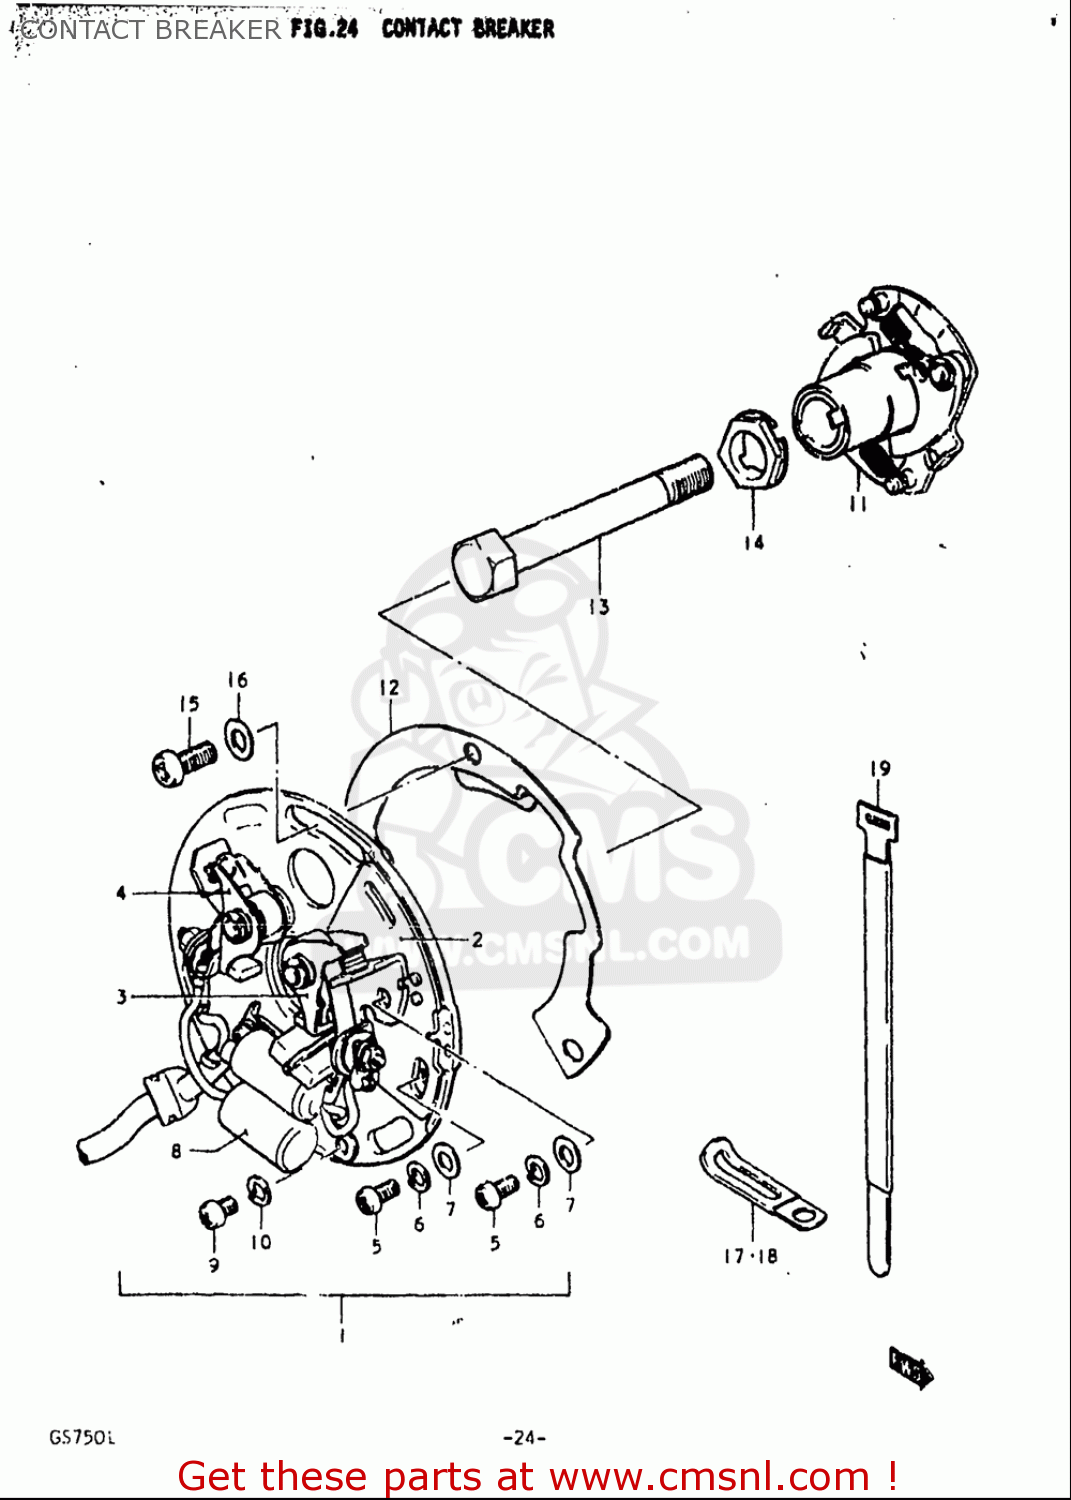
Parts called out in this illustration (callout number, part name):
1	BREAKER ASSEMBLY,CONTACT
2	PLATE,CONTACT POINT
3	POINT ASSY,R
4	POINT ASSY,L
5	SCREW(4X10)
6	WASHER,LOCK
7	WASHER
8	CONDENSER
9	SCREW 4X6
10	WASHER,LOCK
11	GOVERNOR ASSEMBLY
12	PLATE,IGNITION TIMING
13	BOLT
14	WASHER
15	SCREW(5X12)
16	WASHER
17	CLAMP(L:65)
18	CLAMP(L:120 T:1.0)
19	CLAMP
